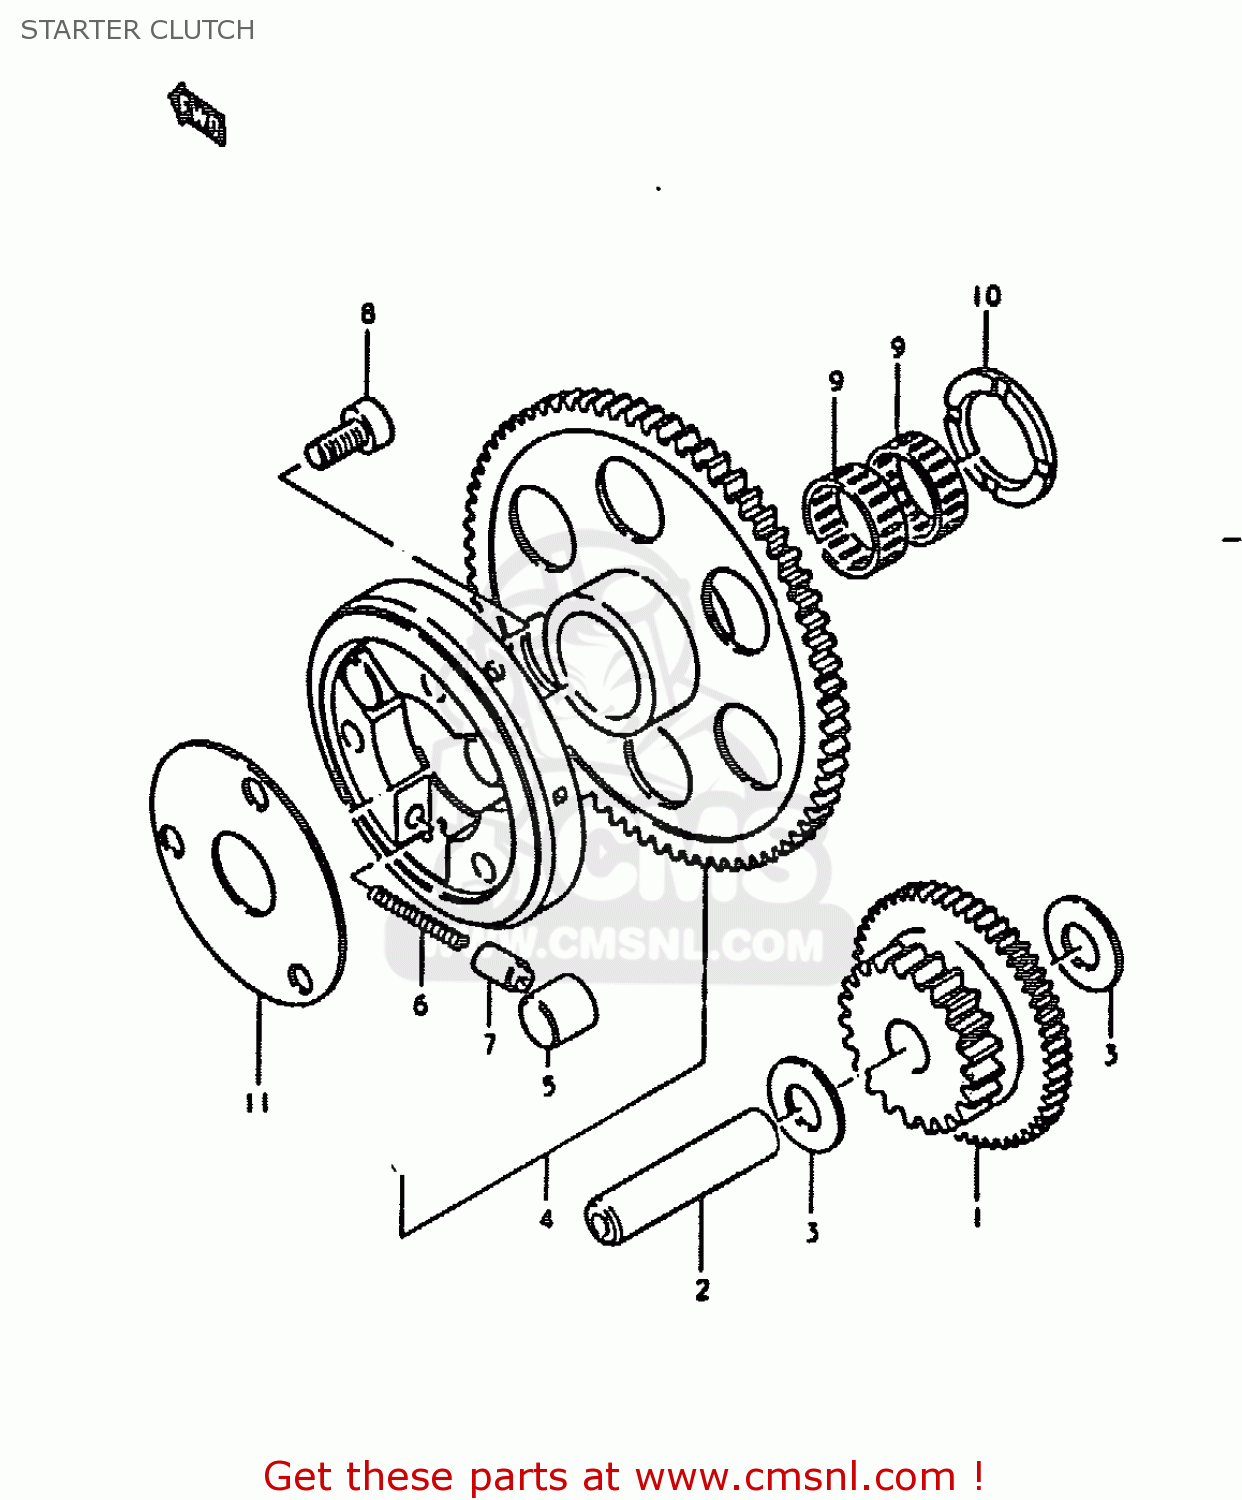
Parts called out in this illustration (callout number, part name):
1	GEAR,STARTER IDLE
2	PIN(7.4X13X56)
3	WASHER(13.3X25X0.85)
4	CLUTCH SET,STARTER
5	ROLLER(15X13)
6	SPRING
7	PIECE,PUSH
8	BOLT
9	BEARING(25X29X9.9)
10	WASHER(25X38X2.5)
11	SHIM,STARTER CLUTCH HUB
